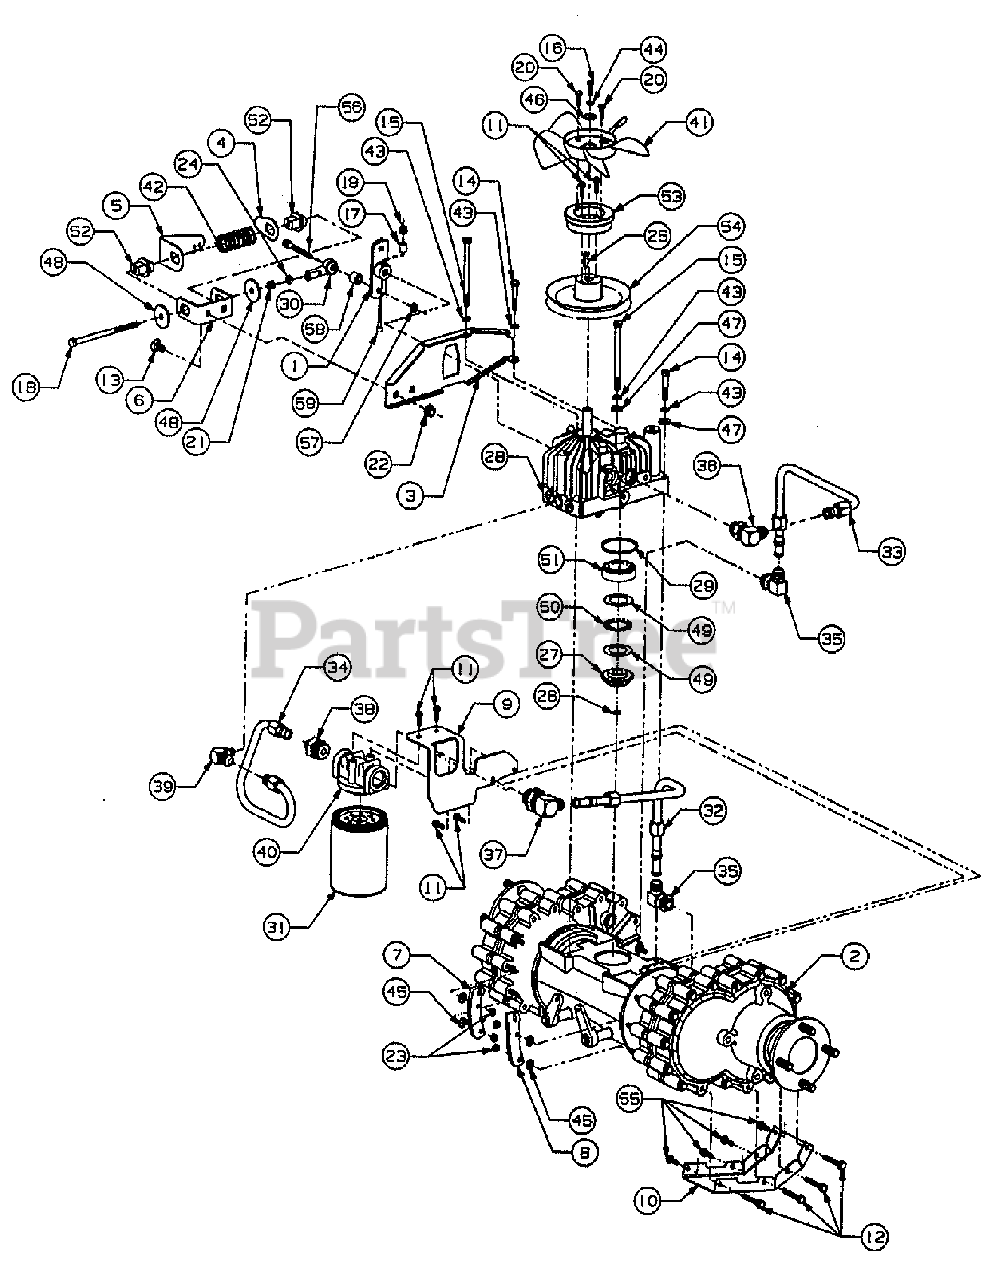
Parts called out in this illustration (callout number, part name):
1	Lever, Forward & Reverse
2	Transmission Assembly, Complete
3	Plare, Neutral Mechanism
4	Stop, Switch
5	Mount, Switch
6	Bracket, Neutral Mechanism
7	Plate, Left Cable
8	Plate, Right Cable
9	Bracket, Oil Filter
10	Plate, Skid
11	Screw, Hex Wash Hd Tapp, 1/4-20 x .75
12	Screw, Hex Wash Hd Tapp, 1/4-20 x 2.31
13	Bolt, Sht Nk Carriage, 3/8-16 x .75 Gr 5
14	Screw, Hex Cap, 5/16-18 x 2.0 Gr 5
15	Screw, Hex Cap, 5/16-18 x 4.75 Gr 5
16	Screw, Hex Cap, M6-1.0 x 20mm Gr 10.9
18	Screw, Hex Cap, 5/16-24 x 5.37 Gr 5
19	Nut, Nylon Lock, 10-24
20	Screw, Hex Cap w/Patch 1/4-20 x .75 Gr 5
21	Nut, Hex Insert Lock, 5/16-24
22	Nut, Hex Flanged Lock, 3/8-16
23	Nut, Hex Top Lock 1/4-20
24	Nut, Hex Jam, 5/16-24 Gr 5
25	Key, Square 5mm x 5mm x 25mm
26	Ring, Snap .500 Dia Shaft
27	Gear, Input Pinion 20T
28	Pump, Hydrostatic
29	O-Ring, 2.237 ID x .103 Thk
30	Rod End, Spherical
31	Filter, Oil
32	Tube, Filter Inlet
33	Tube, Return
34	Tube, Hydro Inlet
35	Elbow, 90 Deg w/O-Ring
35	O-Ring, 1/2 OD Tube
36	Elbow, 90 Deg w/O-Ring
36	O-Ring, 3/4 OD Tube
37	Elbow, 90 Deg w/O-Ring
37	O-Ring, 3/4 OD Tube
38	Connector, Straigh w/O-Ring
38	O-Ring, 3/4 OD Tube
39	Elbow, 90 Deg w/O-Ring
39	O-Ring, 1/4 OD Tube
40	Head, Filter
41	Fan, Hydro 8''
42	Spring, Compression 1.20 OD x 2.70
43	Washer, Lock 5/16
44	Washer, Lock 1/4
45	Washer, Flat, .25 x .62 x .0515 Thk
46	Washer, Flat, .25 x .750 x .119 Thk
47	Washer, Flat, .312 x .750 x .119 Thk
48	Washer, Flat, .206 x .448 x .105 Thk
49	Washer, Thrust, 1.25 x 1.937 x .031 Thk
50	Bearing, Thrust, 1.25 x 1.937 x .0781 Thk
51	Spacer, Input Pinion
52	Guide, Neutral Stop
54	Pulley, Transmission Drive
55	Screw, Hex Wash Hd Tapp, 1/4-20 x .50
56	Screw, Hex Cap 5/16-18 x 1.38 Gr 5
57	Nut, Hex Flange Lock, 5/16-18 Gr 5
58	Spacer, .317 ID x .625 OD x .343
59	Screw, Socket Hd, 10-24 x 1.5
